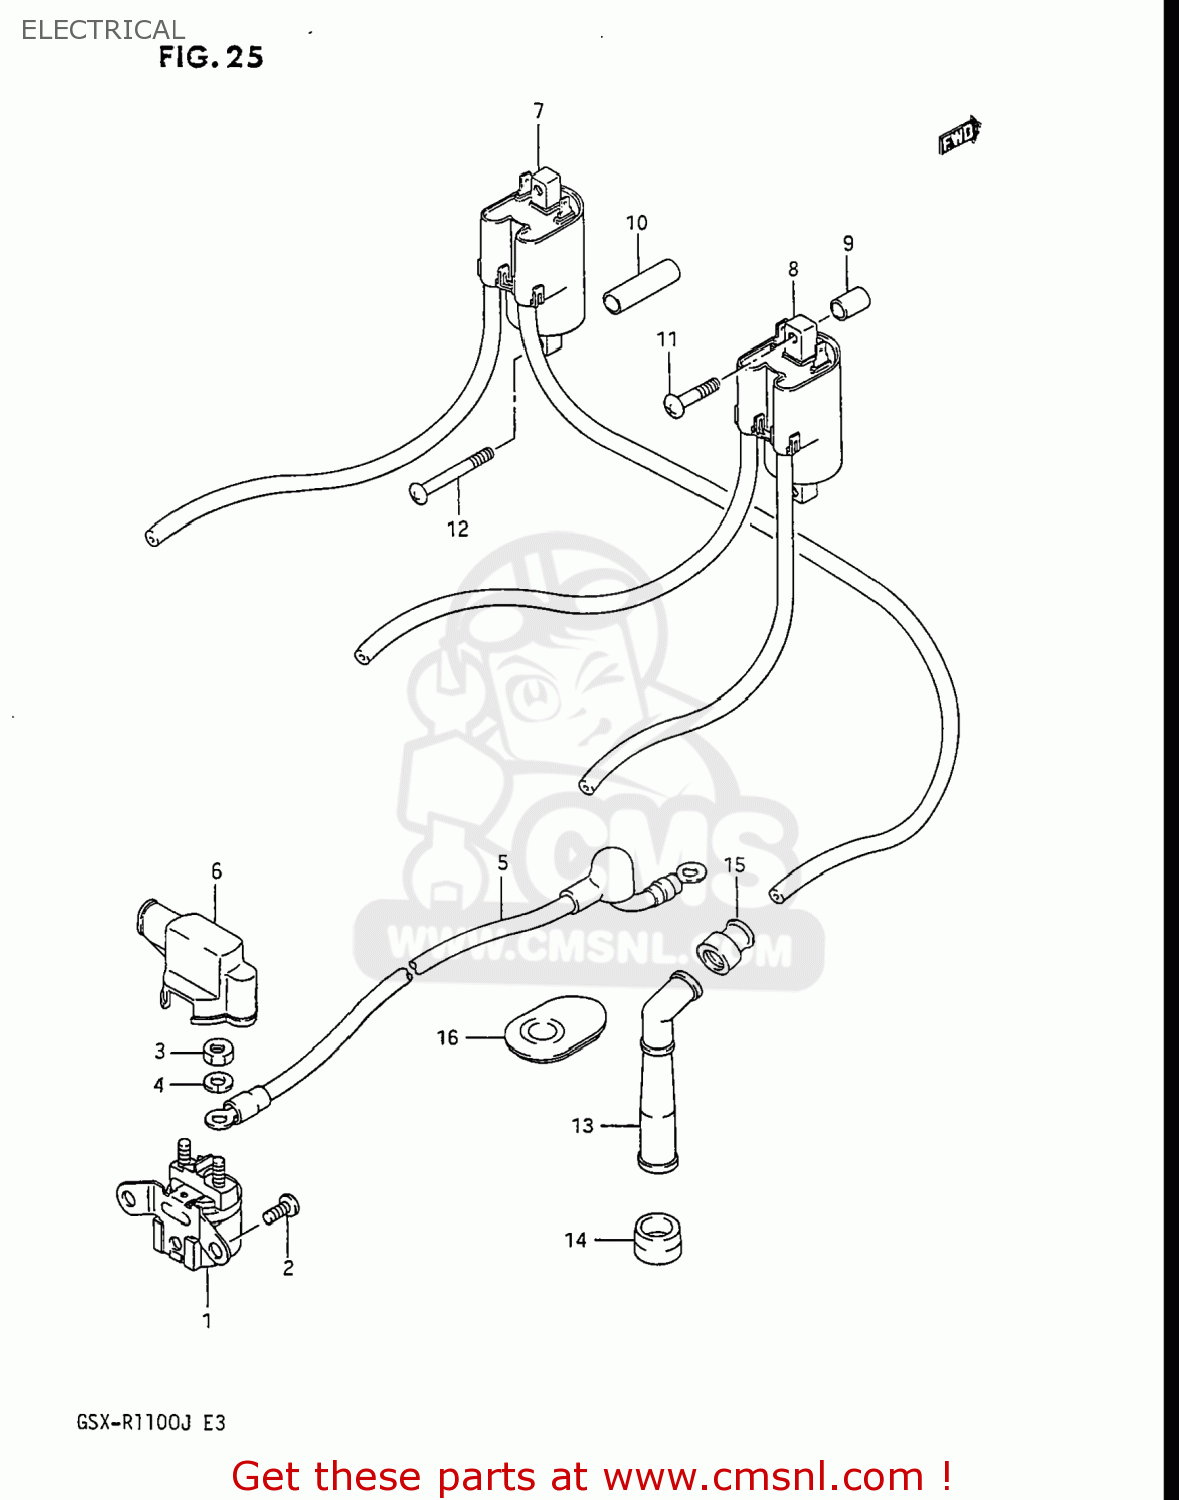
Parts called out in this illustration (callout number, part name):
1	RELAY ASSY,STARTING MOTOR
2	SCREW
3	NUT
4	WASHER,LOCK
5	WIRE,STARTER MOTOR LEAD
6	CAP,STARTER RELAY
7	COIL ASSEMBLY,IGNITION
8	COIL ASSEMBLY,IGNITION
9	SPACER
10	SPACER(6.5X10.5X40)
11	SCREW
12	SCREW
13	CAP,SPARK PLUG
14	SEAL,SPARK PLUG
15	SEAL,SPARK PLU
16	COVER,SPARK PLUG CAP
